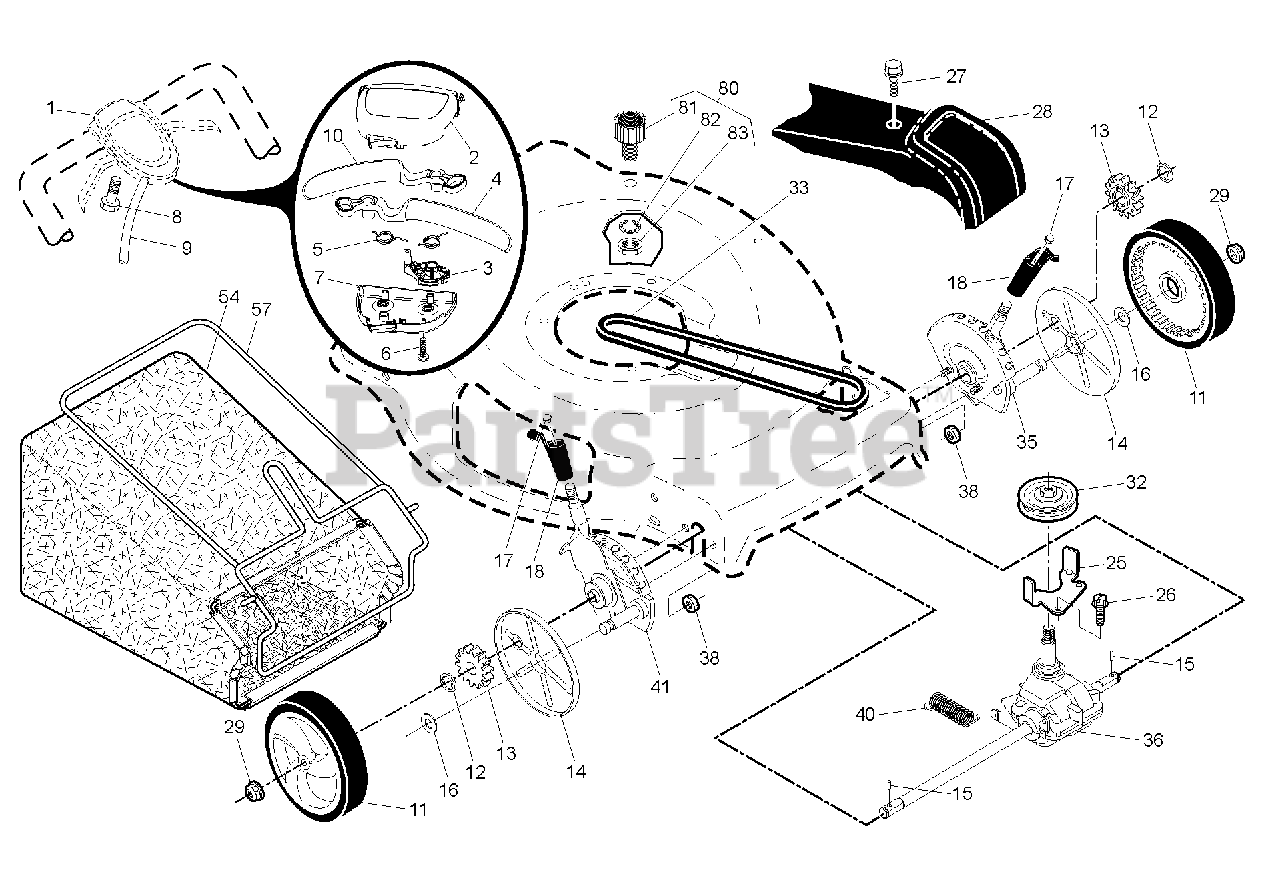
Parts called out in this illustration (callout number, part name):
3	CAM.VSC.DRIVE.CABLE
5	SPRING, DRIVE CONTROL
6	COVER.DRIVE.LOWER.VSC.BLACK
11	E-RING 7/16 RE
12	PINION.14.TEETH.FGD
13	COVER.DUST.WHEEL
14	PAWL, DRIVE
15	WASHER FLUT
18	SCREW, PHILLIPS HEAD 10 X 5/8
25	BRACKET.BELT.GUIDE.22+FGD.BZP
29	NUT.HEX.FLANGE.3/8-16.LOCKNUT
32	RP PULLEY.DRIVE.EZ
38	NUT.HEX.FLANGE.1/4
57	FRAME.GBAG.22PLUS
80	KIT.WASH-OUT.PORT
81	FITTING, HOSE, WATER WASHOUT
82	WASHER.LOCK.INTERNAL.TOOTH
83	LOCKNUT.HEX.WITH.O-RING
